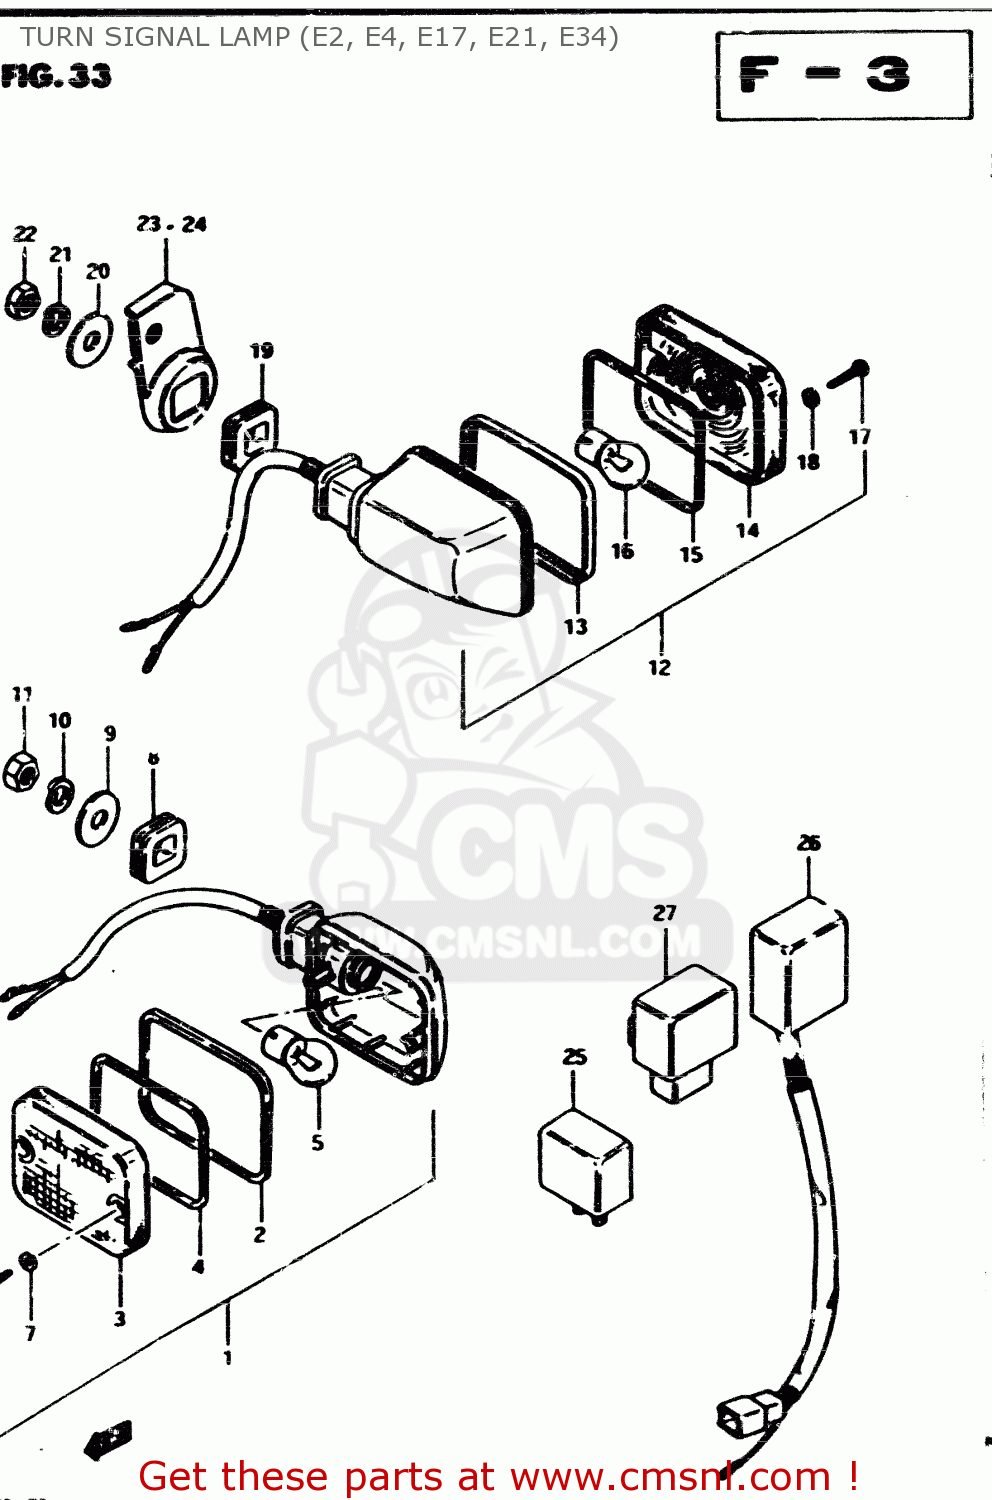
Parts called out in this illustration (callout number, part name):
1	LAMP ASSY,FR T
2	RIM
3	LENS
4	GASKET (NAS)
5	BULB(12V21W)
6	SCREW
7	GASKET (NAS)
8	CUSHION
9	WASHER (10.5X30X2.3)
10	LOCK WASHER
11	NUT
12	LAMP, REAR TURN SIGNAL
13	RIM
14	LENS
15	GASKET (NAS)
16	BULB(12V21W)
17	SCREW
18	GASKET (NAS)
19	CUSHION
20	WASHER (10.5X30X2.3)
21	LOCK WASHER
22	NUT
23	BRACKET,REAR TURN SIGNAL
24	BRACKET,REAR TURN SIGNAL
25	RELAY ASSY,TURNSIGNAL
26	UNIT,TURN SIGNAL CONTROL
27	UNIT,TURN SIGNAL CONTROL
